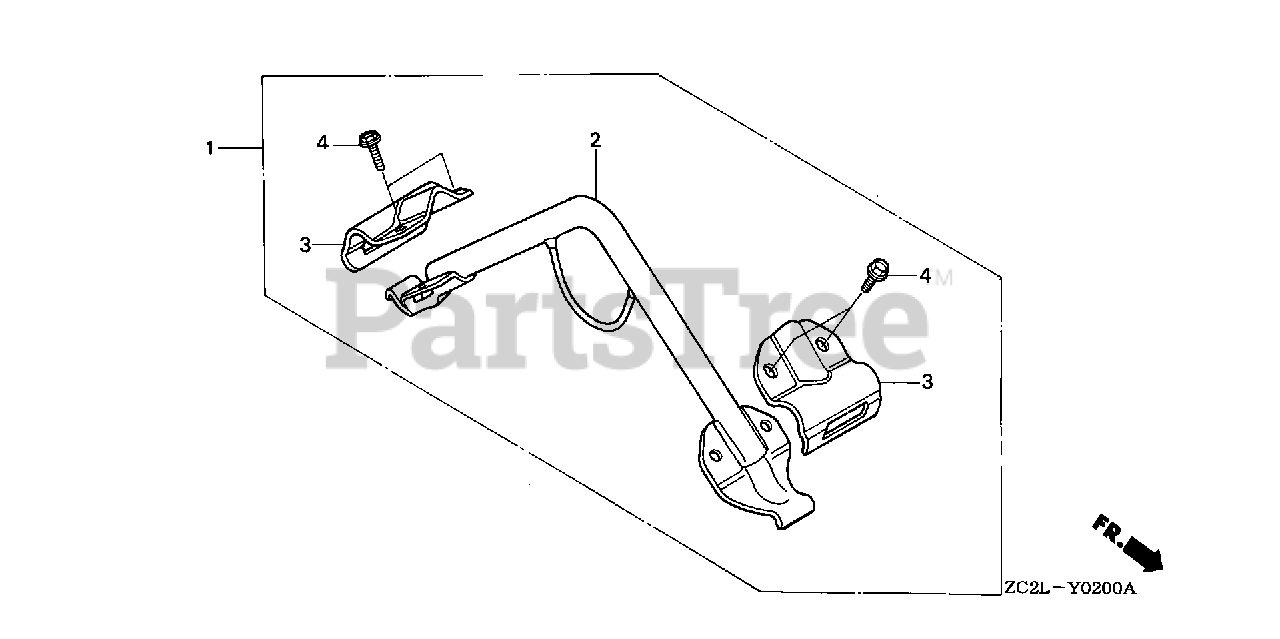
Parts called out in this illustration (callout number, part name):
1	HANGER KIT
2	HANGER
3	BRACKET, HANGER (UPPER)
4	BOLT, FLANGE (8X16)
